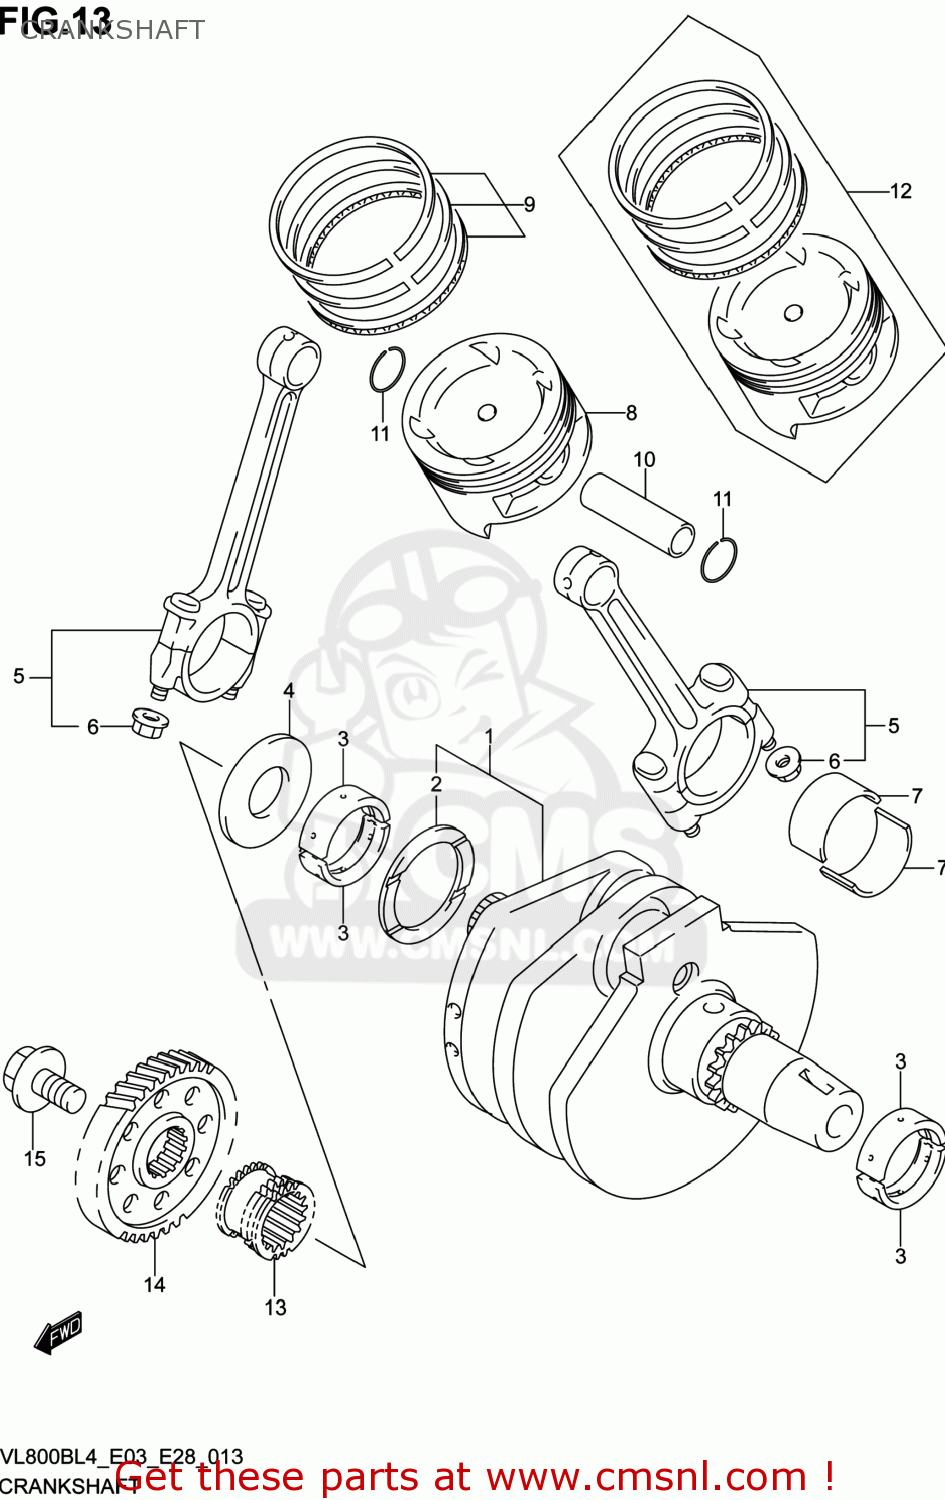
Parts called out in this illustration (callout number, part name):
1	CRANKSHAFT SET
2	WASHER(48.1X64X1.94)
3	BEARING,CRANKSHAFT
4	WASHER,CRANK THRUST
5	CONNECTING ROD ASSY
6	NUT
7	BEARING,CRANK PIN
8	PISTON
9	RING SET,PISTON
10	PIN,PISTON
11	CIRCLIP,PISTON PIN
12	PISTON SET,OS 0.5
13	SPROCKET,CAM CHAIN DRIVE,R
14	GEAR,PRIMARY DRIVE
15	BOLT(12X28)
